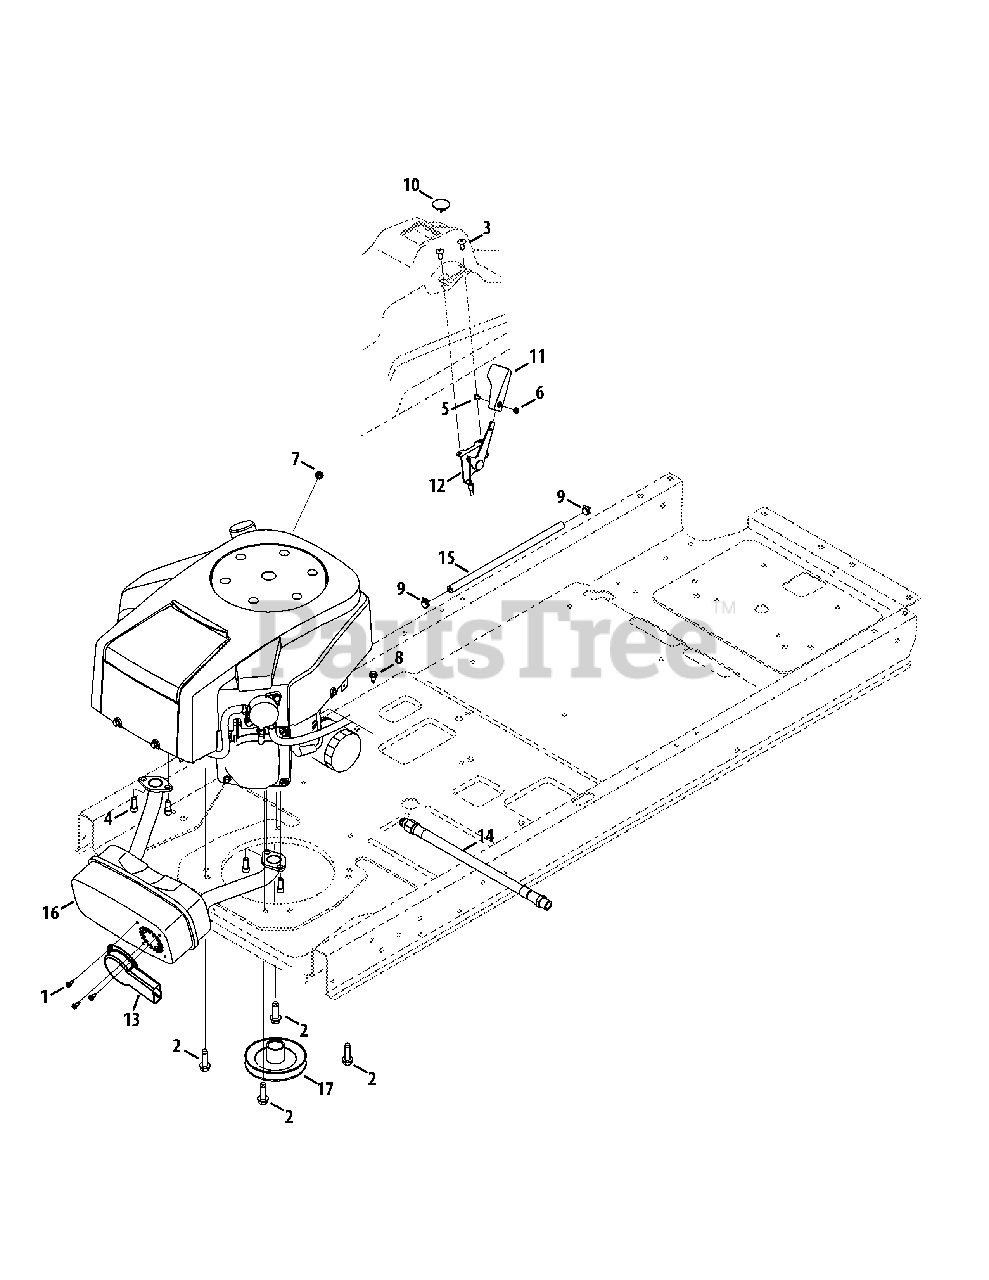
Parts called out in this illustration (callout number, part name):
1	Hex Washer Screw, #8-18 x .500
2	Hex Washer Screw, 3/8-16 x 1.00
3	Screw, 1/4-20 x .50
4	Socket Head Screw, 5/16-18 x .750
5	Screw, #8-32 x .375
6	Hex Nut, #8-32
7	Flange Lock Nut, 1/4-20
8	Hex Washer Screw, 1/4-20 x .625
9	Hose Clamp, .490 Dia.
10	Choke Plug
11	Throttle Control Knob
12	Throttle/Choke Control Cable
13	Muffler Deflector Long
14	Oil Drain Hose
15	Fuel Hose, 1/4
16	Twin Muffler
17	Engine Pulley
